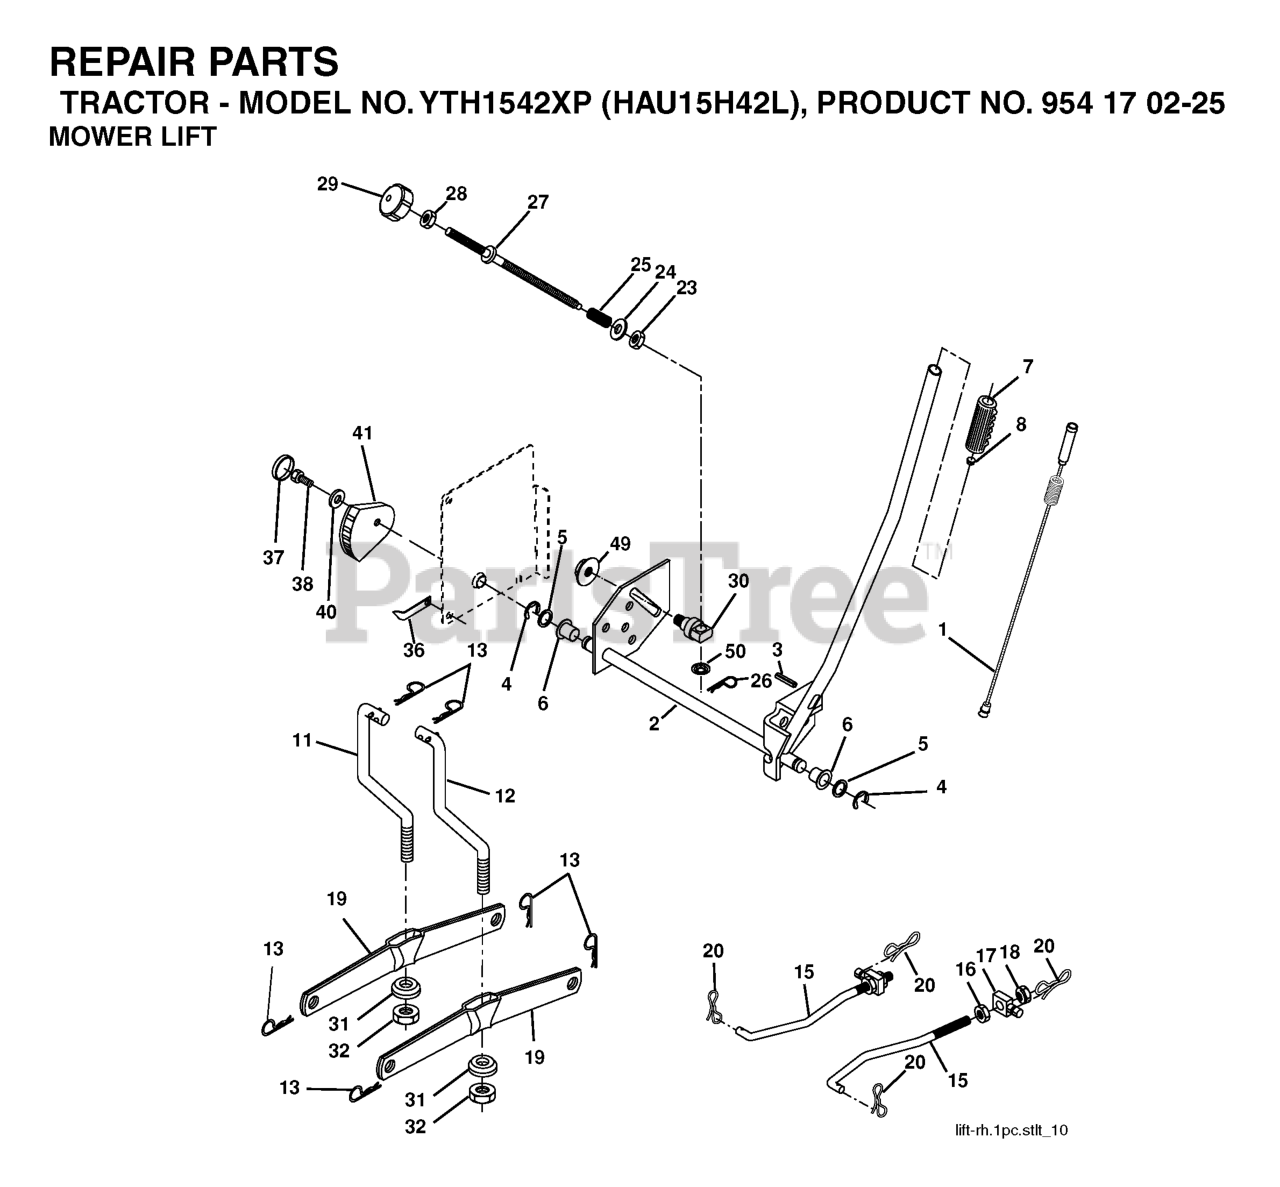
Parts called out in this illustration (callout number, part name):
2	SHAFT.ASM.LIFT.YT
3	PIN.GROOVE.5/16
4	RETAINING RING LT
6	BEARING.NYLON
7	GRIP HANDLE
8	PLUNGER BUT KIT
11	LINK LIFT LH
12	LINK LIFT RH
13	RETAINER-SPRNG RB
15	LINK.SUSPENSION.FRONT
16	NUT.HEX.JAM.1/2-13
18	NUT.LK.W/WSH.1/2.
19	ARM.REAR.SUSPENSION
20	PIN.COTTER.7/16.BOW TI.
26	RETAINER CLIP
27	ROD ADJ LIFT
28	NUT
29	KNOB INF 3/8-16
31	BEARING.PIVOT.LIFT
32	NUT CROWNLOCK 3/8-24
36	POINTER, HEIGHT INDICATOR(2 2)
38	SCREW 5/16-18X1
41	IND. HEIGHT STLT
49	NUT
50	NUT PUSH M
